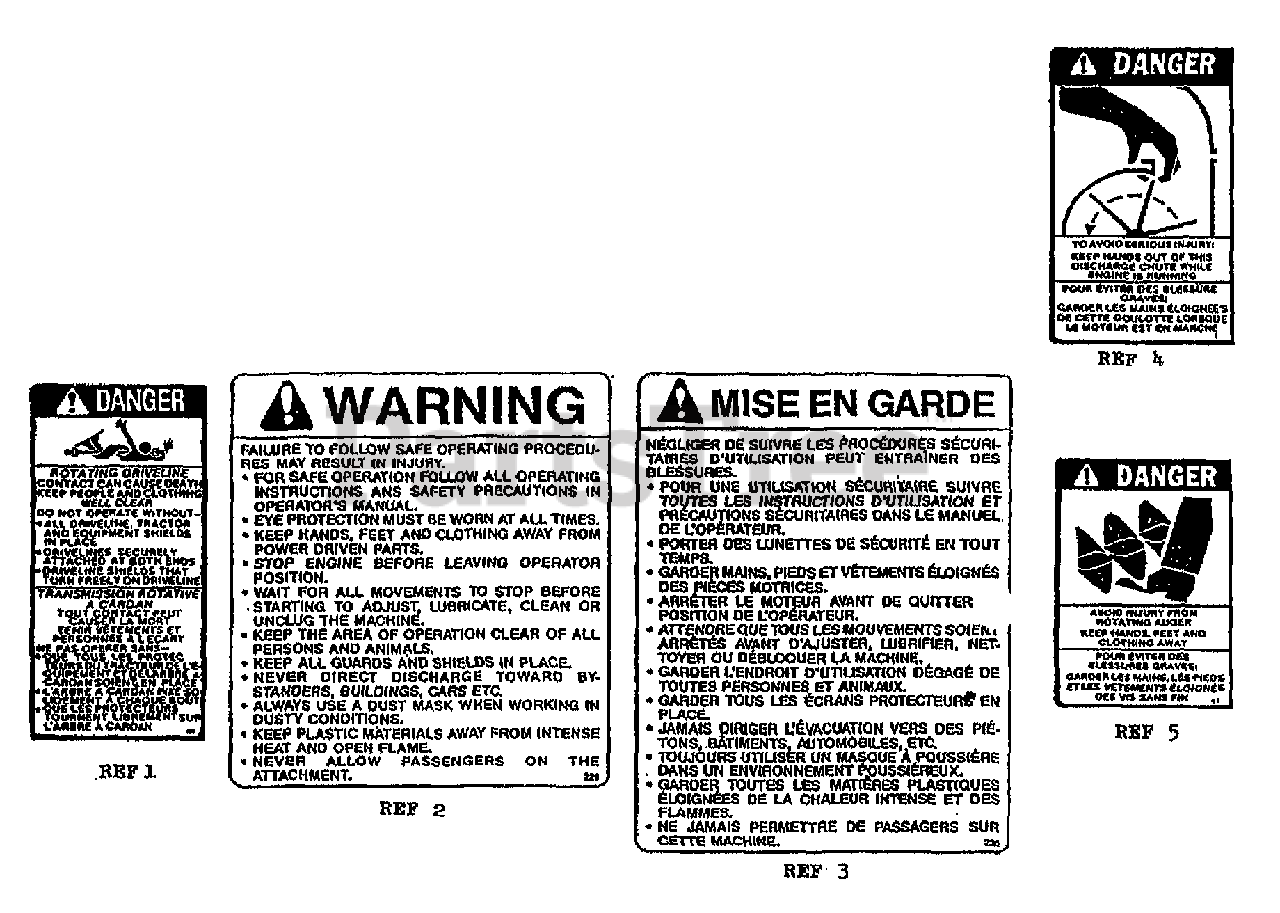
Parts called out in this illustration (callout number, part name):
1	DECAL-DANGER
2	DECAL-WARNING #229
4	DECAL-DANGER
5	DECAL-DANGER
